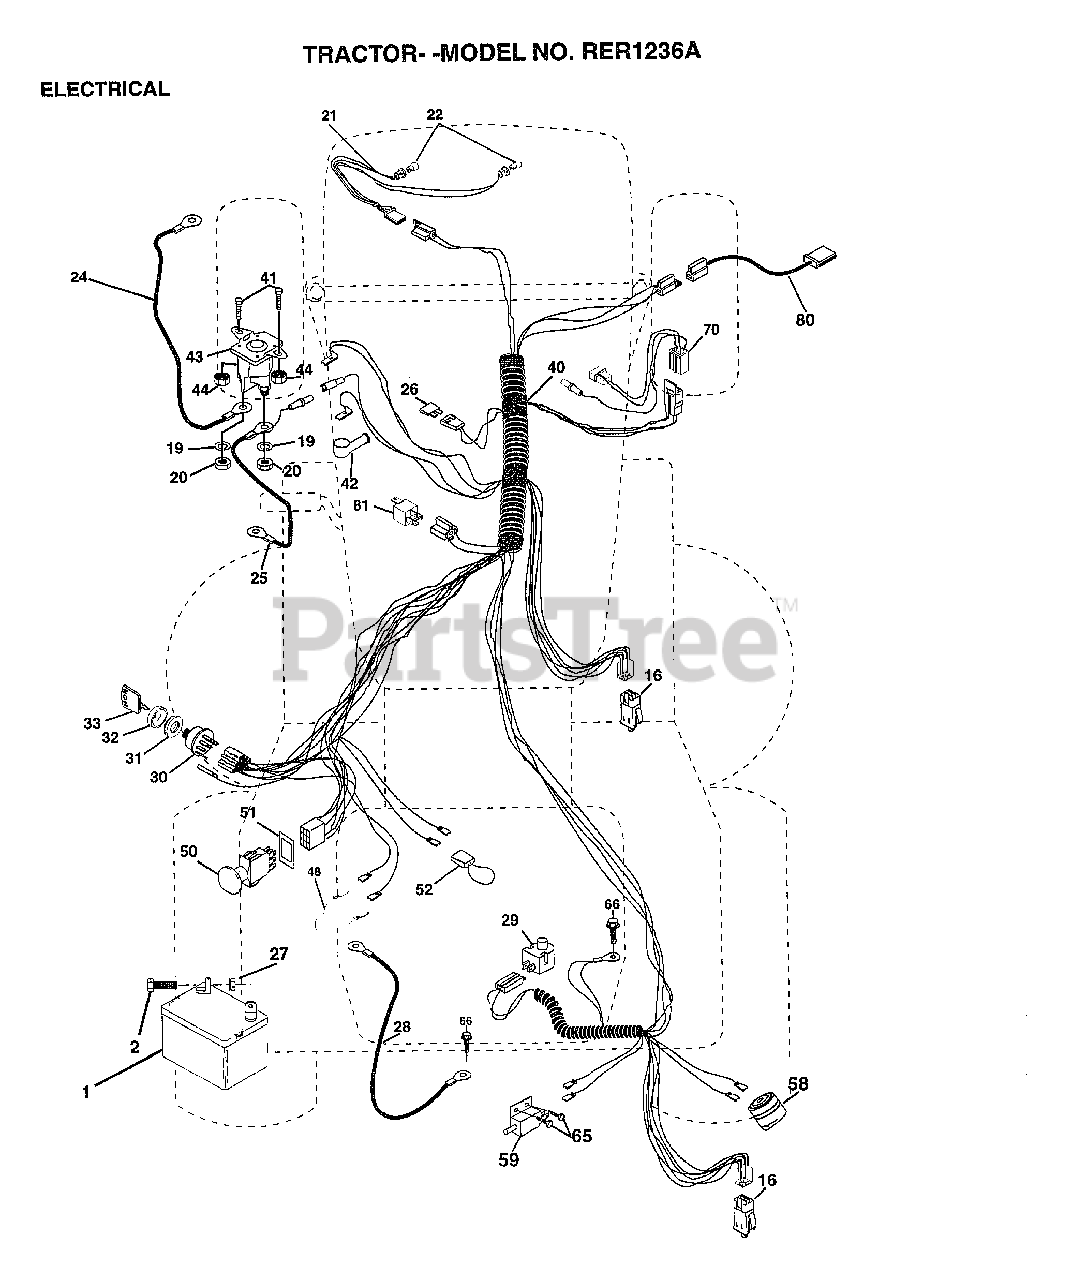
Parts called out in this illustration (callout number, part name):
2	BOLT LT
16	SWITCH INTERLOCK
20	NUT
21	HARNESS.ASM.LIGHT W/4152J
22	HEADLAMP BULB
24	"CABLE T, BATTERY"
25	CABLE.BATTERY.CRD
26	FUSE.15 AMP
27	NUT
28	"CABLE.GRD.6GA/18""BLACK"
29	SWITCH.PLUNGER
30	SWITCH IGN 4POS
31	NUT IGNITION
32	COVER KEY SWITCH
33	KEY
40	HARNESS.IGN.CRD.ELECT
41	BOLT HXHD FIN
44	NUT HXKEP 1/4X20
48	ADAPTER AMMETER
50	PTO SWITCH.RED
51	RING RETAIN PTO
52	PROTECTION LOOP
59	SWITCH.FBI.CRD
65	SCREW
66	SCREW LT
70	HARNESS.ENGINE
80	HARNESS.CLUT.EVX.
81	RELAY ASSY T
